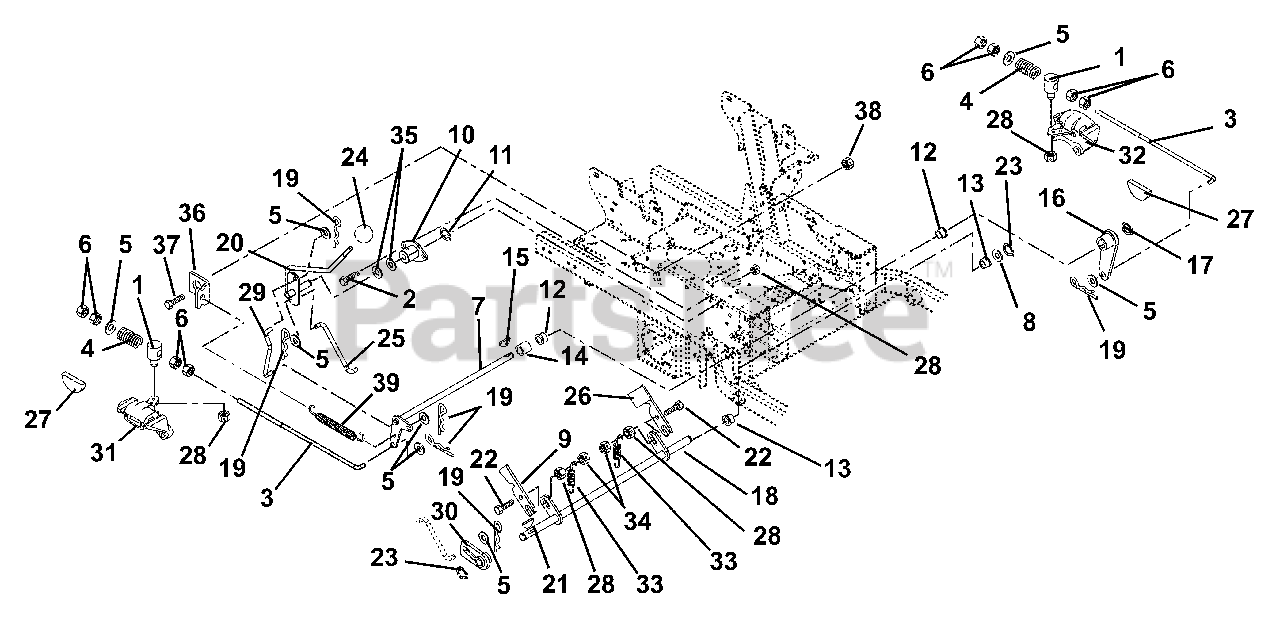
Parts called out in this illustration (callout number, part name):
1	PIN, PIVOT/TRUNNION
2	@BLT-HEX .31-18X.75 GR5 YWZC
3	ROD - BRAKE 12 INCH
4	SG-COMP .142 X .710 X 2.00
5	@WSHR-FL-STL.406X.812X.065 YWZ
6	@NUT-HEX .38-16 YWZC
7	WMT, BRAKE CROSS SHAFT
8	WSHR-FL-STL .505X1.00X.062YWZC
9	SLIDE, INTERLOCKING BRAKE
10	BUSHING, FLANGED
11	RG-RTNG-EXT .625X.050
12	BSHG-FLG .762X1.0X.580X1.48 NY
13	BSHG-FLG .515X.750X.745X1.00NY
14	BSHG-SLV .750X1.000X.750
15	KEY-WDRF .19X.75 HRD #9
16	WMT, BRAKE ARM
17	RG-RTNG-EXT .689X.078
18	WMT, MECHANICAL BRAKE
19	PIN-HAIR, ENDRIES #25 YWZC
20	WMT, BRAKE ACTUATING
21	KEY-WDRF .13X.63 HRD#5
22	@BLT-HEX .31-18X1.25 GR5 YWZC
23	RG-RTNG-EXT .500X.050 (SNAP)
24	KNOB-STEERING LOCK
25	LINKAGE, BRAKE ACTUATING
26	INTERLOCK, SAFETY SWITCH
27	PAD SET, DISK BRAKE
28	@NUT-LK-TOP-FLG .31-18 YWZC
29	LINKAGE, BRAKE ACTUATING
30	WMT, PARKING BRAKE HUB
31	BRAKE, RH CALIPER
32	BRAKE, LH CALIPER
33	SG-TENS .061 X .50 X 3.0 WLD 4
34	@NUT-LK-CTR .31-18 YWZC
35	WSHR-FL-STL .630X1.250X.062 YZ
36	BRACKET, SPRING MOUNTING
37	@BLT-HEX .50-13X1.00 GR5 YWZC
38	@NUT-LK-TOP-FLG .50-13 YWZC
39	SPRING, EXT
